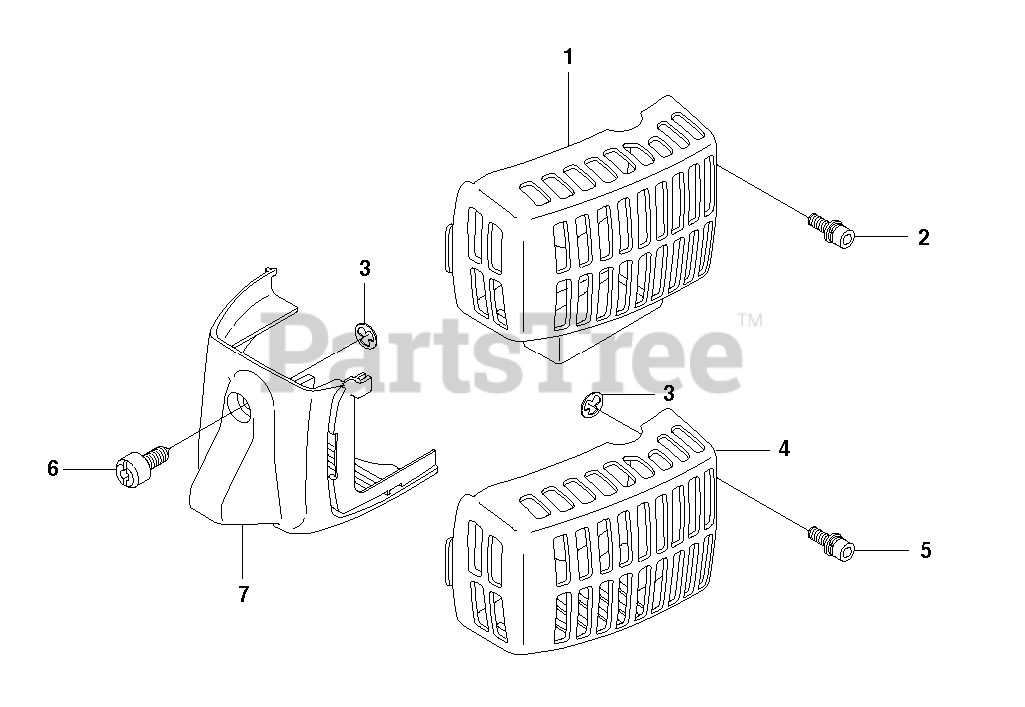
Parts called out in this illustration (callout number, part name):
1	HEAT SHIELD
4	MUFFLER COVER
7	CYLINDER COVER
